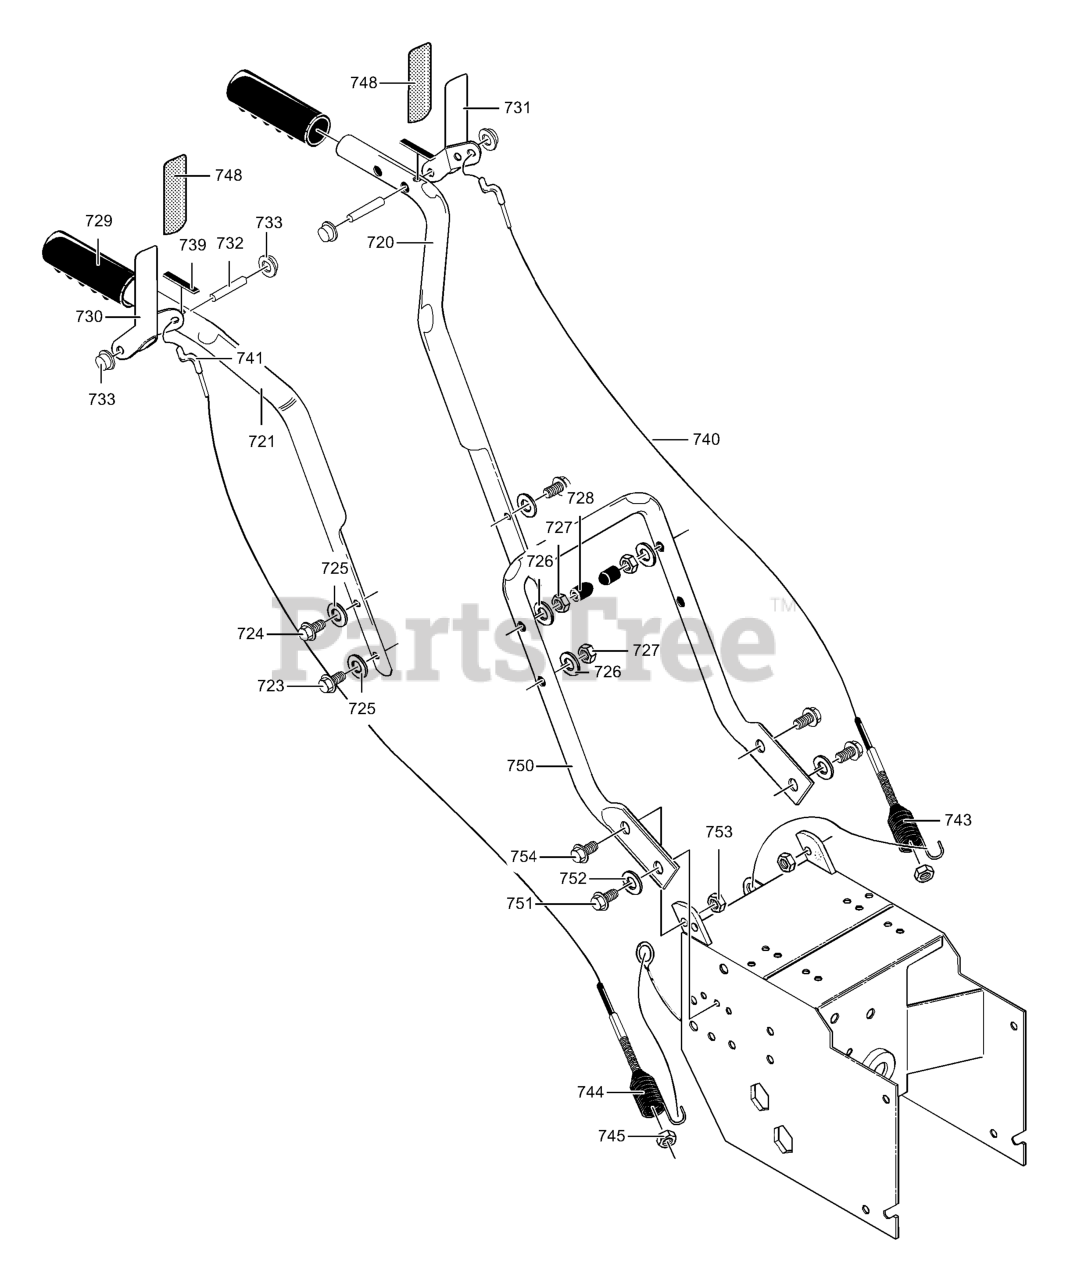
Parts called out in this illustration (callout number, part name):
720	HANDLE, UPPER LH
721	HANDLE, UPPER RH
723	SCREW, 3/8-16 x 2.00
724	SCREW, 3/8-16 x 3.00
725	WASHER, FLAT
726	WASHER, .38ID
727	NUT, 3/8-16 REGHXCTRLK
728	STOP, PLASTIC
729	GRIP, HANDLE
730	ASSY, CLUTCH LEVER RH
731	ASSY, CLUTCH LEVER LH
732	PIN, PIVOT CLUTCH
733	NUT, PUSH ON CAP
739	BUMPER, REC
740	CABLE, CLUTCH
741	CABLE, CLUTCH
743	SPRING, TENSION
744	SPRING, AUGER CLUTCH
745	NUT, 1/4-20 HEX NYLOCK
748	GRIP, CLUTCH HANDLE
750	HANDLE, LOWER
751	SCREW, 5/16-18 x 0.75
752	WASHER, .31X.58X.08
